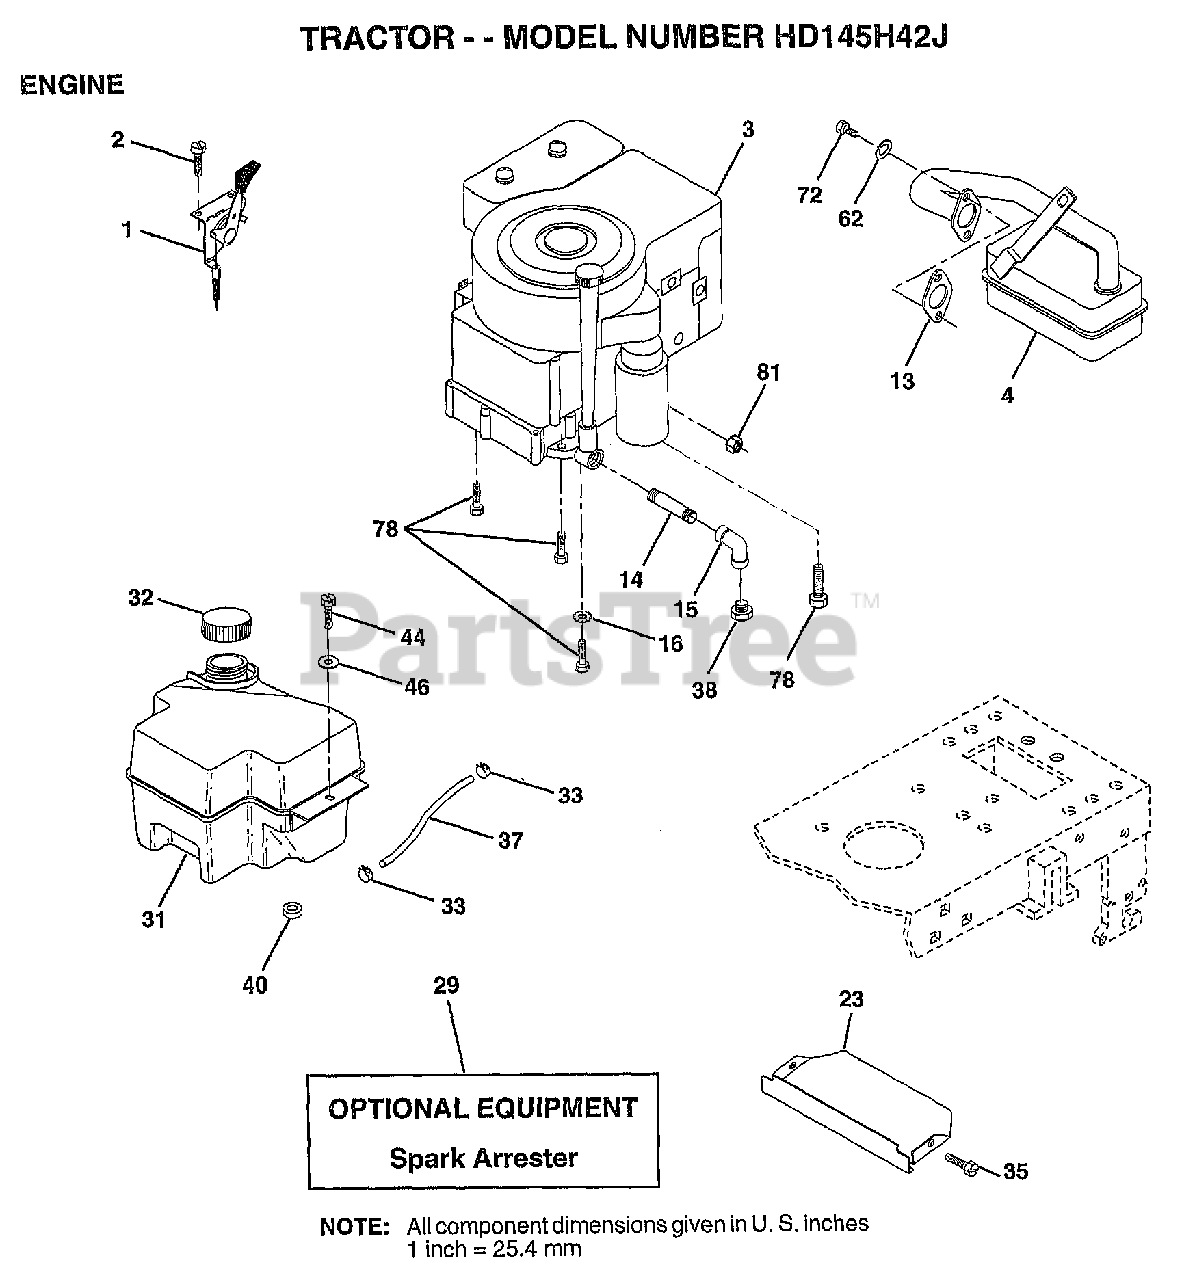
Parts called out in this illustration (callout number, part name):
1	CONTROL THROTTLE
2	SCREW LT
4	MUFFLER
13	GASKET ENG 1 313 LD TIN PLATED
14	PIPE NIPPLE
15	ELBOW
16	LOCKWASHER
23	SHIELD.BRN/DBR.GD
31	TANK.FUEL.FRONT.
32	CAP ASM FUEL
33	HOSE CLAMP
35	SCREW
37	LINE FUEL
44	SCREW HEX CRT
46	WASHER
62	LOCKWASHER
72	SCREW
78	SCREW
81	NUT
